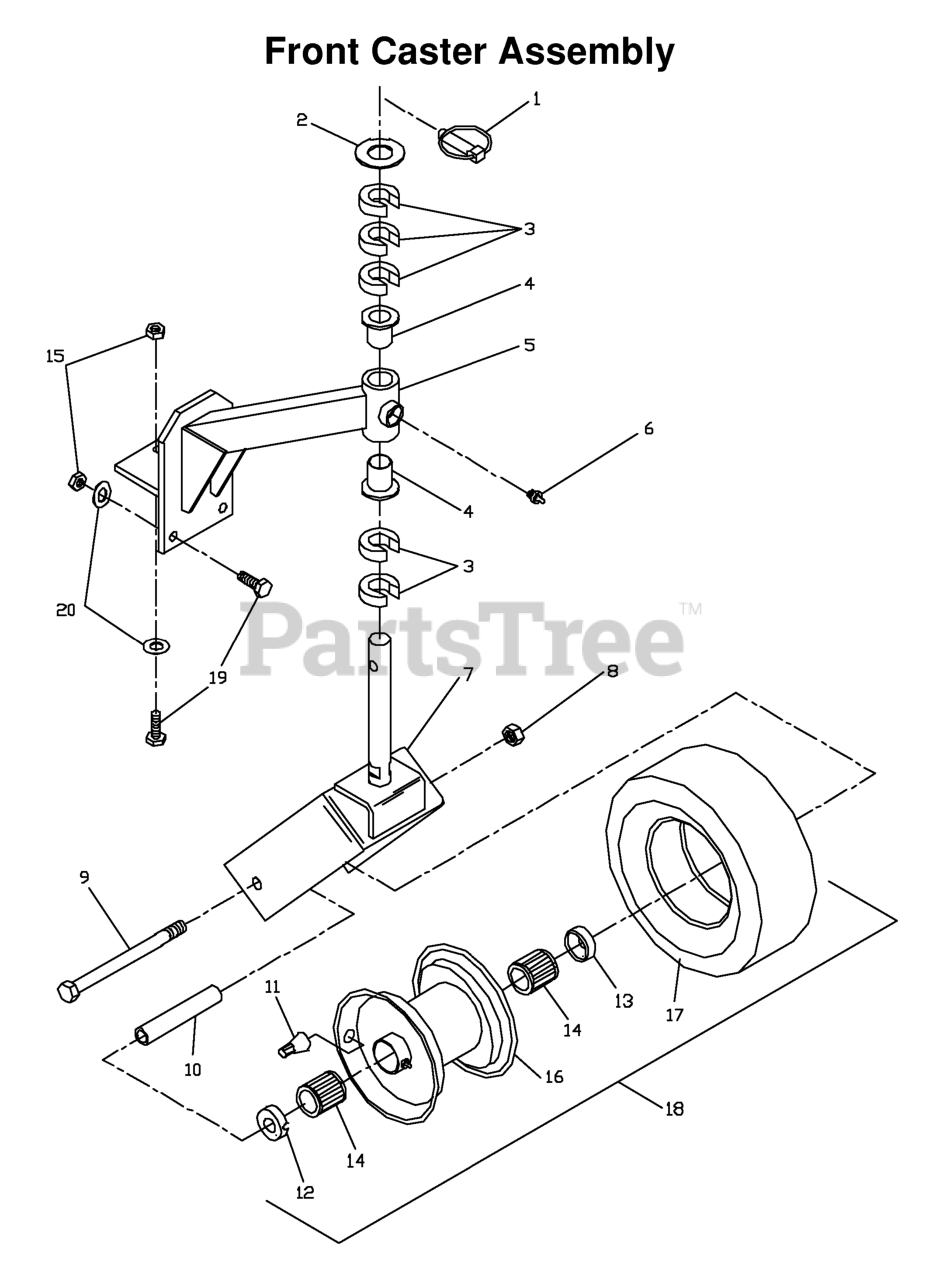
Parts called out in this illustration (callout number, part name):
1	LYNCH PIN 7/16
2	MACHINE BUSHING
4	BUSHING, FLANGED
5	CASTER ARM W/BUSHING
6	ZERK 1/8 NPT
7	CASTER YOKE
8	NUT 1/2-13 HEX NYLOC ZD
9	HCS 1/2C X 5 1/2
11	VALVE STEM TR-412
12	ENDCAP, NOTCHED
13	ENDCAP
14	ROLLER BEARING
15	NUT 3/8C CENTERBLOCK
17	TIRE 9 X 3.5 - 4
18	TIRE/WHEEL.CASTER.9X3.5-4.SMOO
19	HCS 3/8-16X1.GRD.5.ZD
20	WASHER 3/8 FLAT
21	WHEEL CAST. ASM KIT
